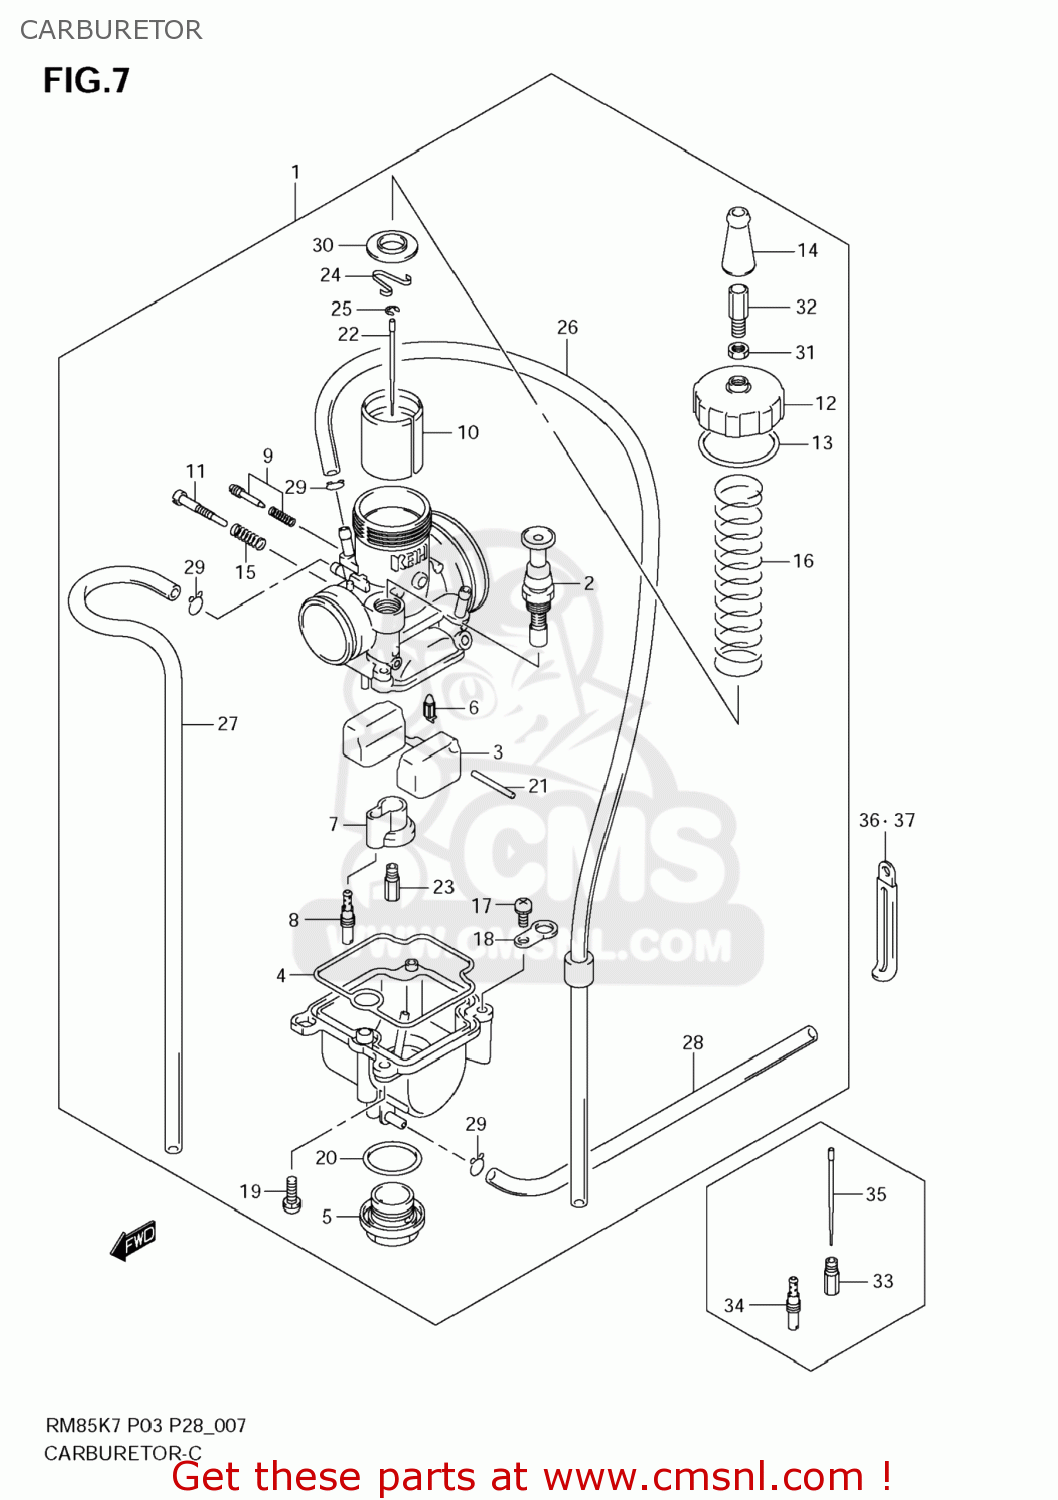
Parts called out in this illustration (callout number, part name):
1	CARBURETOR ASSY
2	VALVE ASSY,STARTER
3	FLOAT ASSY
4	GASKET (NAS)
5	BOLT,DRAIN
6	VALVE ASSY, NEEDLE
7	HOLDER,JET
8	JET,SLOW(50)
9	ADJUST SCREW SET
10	THROTTLE VALVE
11	SCREW,STOP
12	COVER
13	GASKET (NAS)
14	CAP
15	SPRING
16	SPRING
17	SCREW
18	PLATE
19	SCREW
20	O RING
21	PIN,FLOAT
22	NEEDLE(24NAAH)
23	JET,MAIN(128)
24	CLIP
25	CLIP,NEEDLE
26	PIPE ASSY
27	HOSE(4X7X620)
28	HOSE(4X7X620)
29	CLIP
30	PLATE
31	NUT
32	ADJUST BOLT
33	JET,MAIN(115)
34	JET,SLOW(48)
35	NEEDLE(24NAAF)
36	CLAMP(L:45)
37	CLAMP(L:65)
